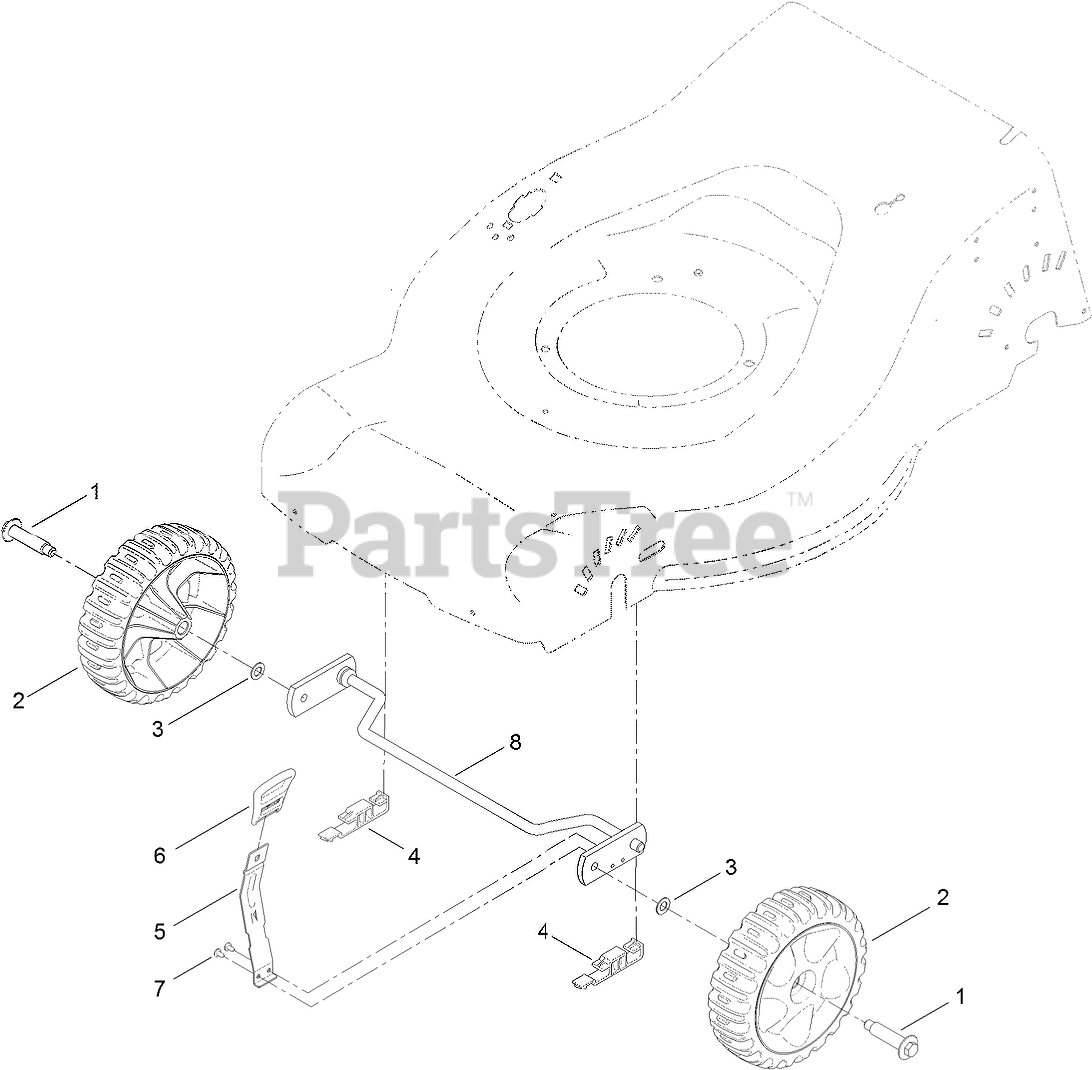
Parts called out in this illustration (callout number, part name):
1	BOLT-SHOULDER
2	7 INCH WHEEL AND TIRE ASM
3	WASHER
4	CLAMP-AXLE, FRONT
5	ARM-SPRING
6	KNOB-HOC
7	SCREW-PAN HEAD, TAP
8	FRONT PIVOT BAR ASM
